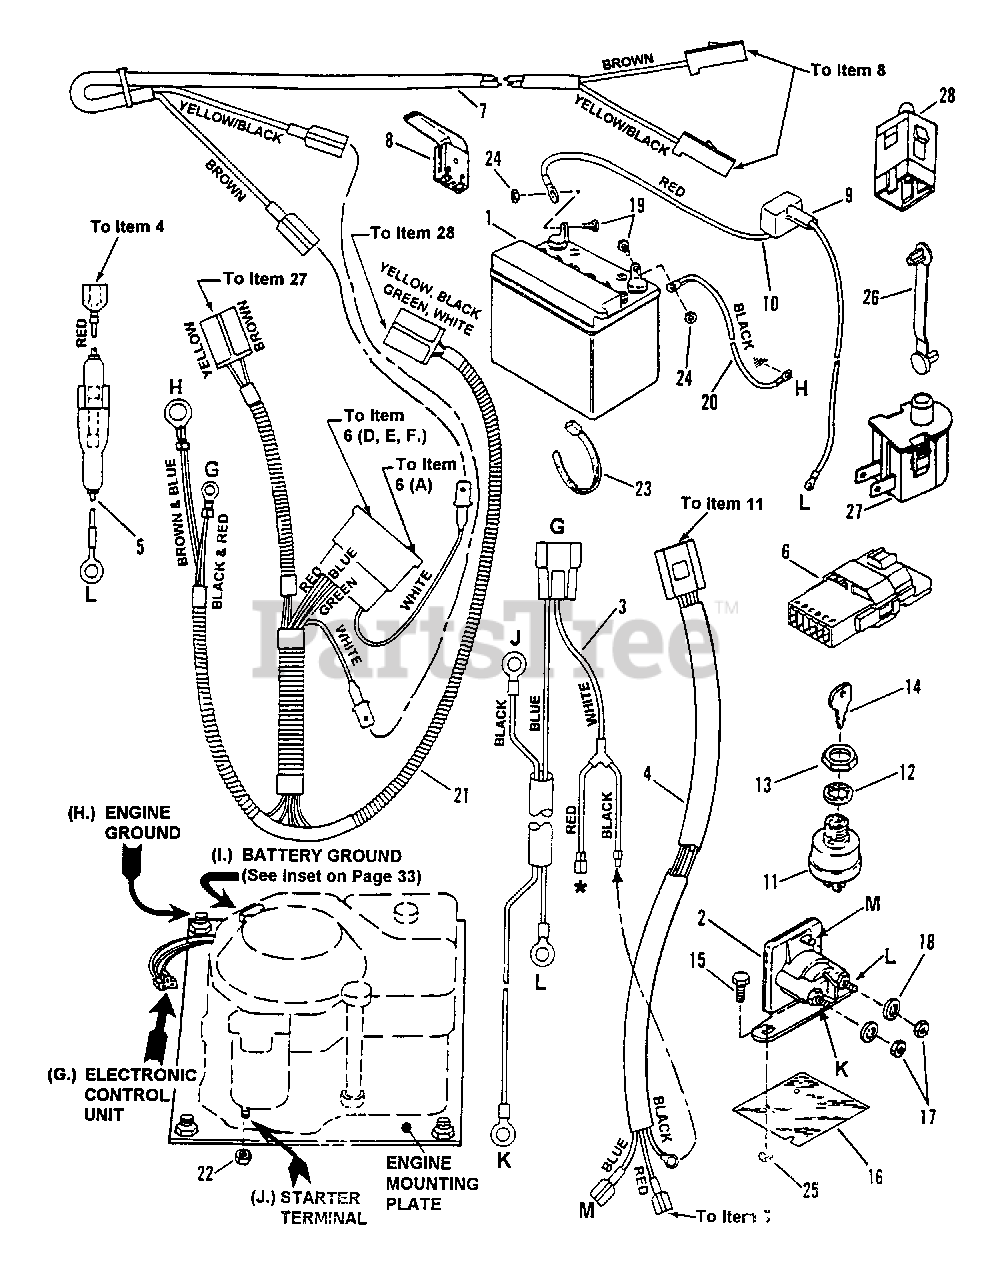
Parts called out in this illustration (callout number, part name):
1	KIT, 12V Dry Charge Battery
2	SOLENOID
3	HARNESS, Starter Wiring
4	HARNESS, Ignition Wiring
5	HOLDER, Fuse
6	INTERLOCK Module
7	HARNESS, (Deck Interlock Wiring)
8	SWITCH, Deck Interlock
9	COVER, Battery Cable
10	CABLE, Positive (Red)
11	SWITCH, Ignition
12	WASHER, 5/8 Internal Tooth Lock
13	NUT, 5/8-32 Hex
14	KEY, Switch
15	SCREW, 1/4-20 x 1/2" Self-Tapping
16	PROTECTOR, Solenoid
17	NUT, 1/4-20 Hex
18	WASHER, 1/4 Internal Tooth Lock
19	SCREW, 1/4-20 x 5/8" Hex Head Cap
20	CABLE, Negative
21	HARNESS, Operator Presence Control (OPC) Wire
22	NUT, 1/4-20 Hex
23	TIE, 7" Long Cable
24	NUT, 1/4-20 Hex Lock
25	RETAINER, 1/4 Bolt
26	TIE, 2" Long Cable
27	SWITCH, Seat
28	SWITCH, Operator Presence Control Traction
